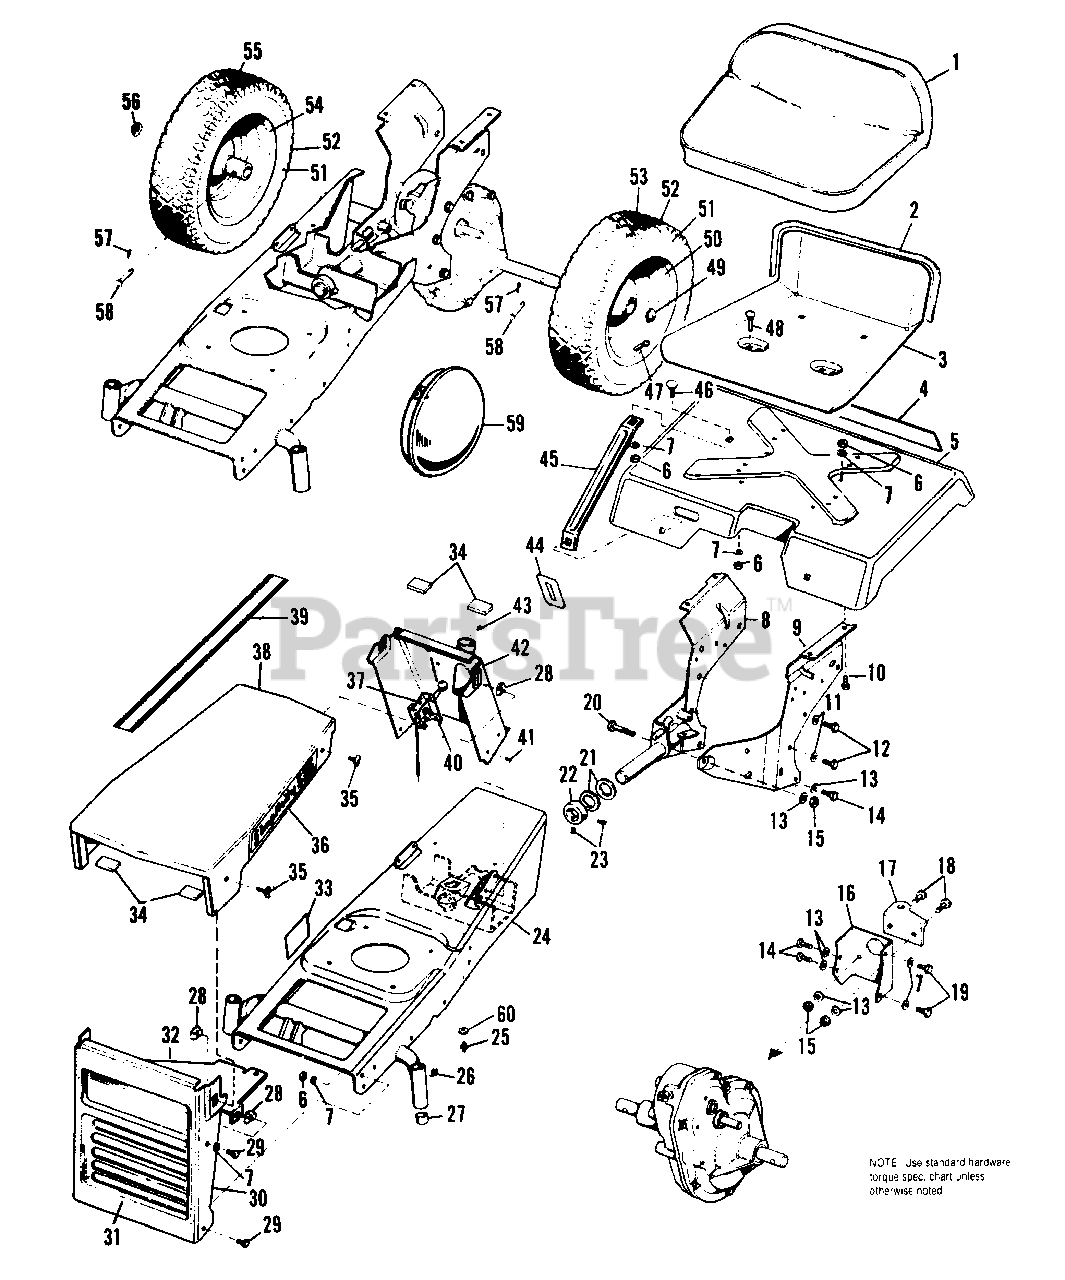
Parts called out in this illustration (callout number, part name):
1	PAD, Seat
2	TAPE, 2 Feet
3	PANEL, Seat
4	EMBLEM, Rear (990776 & 990777 Only)
4	EMBLEM, Rear
5	SUPPORT, Seat (990776 & 990777 Only)
5	SUPPORT, Seat
6	NUT, Hex, Full, 5/16-18
7	LOCKWASHER, 5/16
8	PLATE, Side, R.H. (990776 & 990777 Only)
8	PLATE ASSY., R.H.
9	PLATE, Side, L.H.
10	CAPSCREW, Hex Hd., 5/16-18 x 3/4
11	LOCKWASHER, 7/16
12	CAPSCREW, Hex Hd., 7/16-14 x 3/4
13	LOCKWASHER, 3/8
14	CAPSCREW, Hex Hd., 3/8-16 x 3/4
15	NUT, Hex, Full, 3/8-16
16	BRACKET, Draw Bar
17	CLIP, Draw Bar
18	CAPSCREW, Hex Hd., 3/8-16 x 1
19	CAPSCREW, Hex Hd., 5/16-18 x 1-1/4
20	CAPSCREW, Hex Hd., 3/8-16 x 1-3/4
22	COLLAR, Set
23	SETSCREW, 5/16-18 x 1/2
24	FRAME ASSY.
25	FITTING, Grease
26	FITTING, Grease
28	NUT, Retainer
29	CAPSCREW, Hex Hd., 5/16-18 x 5/8
30	GRILLE (990776 & 990777 Only)
31	DECAL, Grille (990776 & 990777 Only)
31	DECAL, Grille
32	SUPPORT, Grille
33	DECAL, Clutch
34	PAD, Felt
35	SCREW, Thumb, 5/16-18 x 3/4
36	DECAL, Number (990776 & 990777 Only)
36	DECAL, Number
37	CONTROL, Choke (990776 & 990777 Only)
37	CONTROL, Choke
38	HOOD (990776 & 990777 Only)
39	STRIPE, Hood
40	CLIP, Speed
41	SCREW, Hex, Taptite, 1/4-20 x 3/8
42	DASH ASSY.
43	SCREW, Self Tapping, 1/4-20 x 1/2
44	DECAL, Throttle
45	BRACE, Seat Support
46	BOLT, Carriage, 5/16-18 x 1/2
47	VALVE STEM & CAP
48	BOLT, Carriage, 5/16-18 x 3/4
49	BUTTON, Plug
50	WHEEL ASSY., L.H. (990776 & 990777 Only)
50	WHEEL ASSY., L.H.
52	TIRE, Tubeless (990776 & 990777 Only)
53	WHEEL & TIRE ASSY., L.H. (990776 & 990777 Only)
53	WHEEL & TIRE ASSY., L.H.
54	WHEEL ASSY., R.H. (990776 & 990777 Only)
54	WHEEL ASSY., R.H.
55	WHEEL & TlRE ASSY., R.H. (990776 & 990777 Only)
55	WHEEL & TIRE ASSY., R.H.
56	BUTTON, Plug
57	PIN, Cotter. 1/8 x 3/4
58	PIN
59	CAP, Hub, Rear
60	WASHER, Plain, #10 (990595 & 990596 Only)
